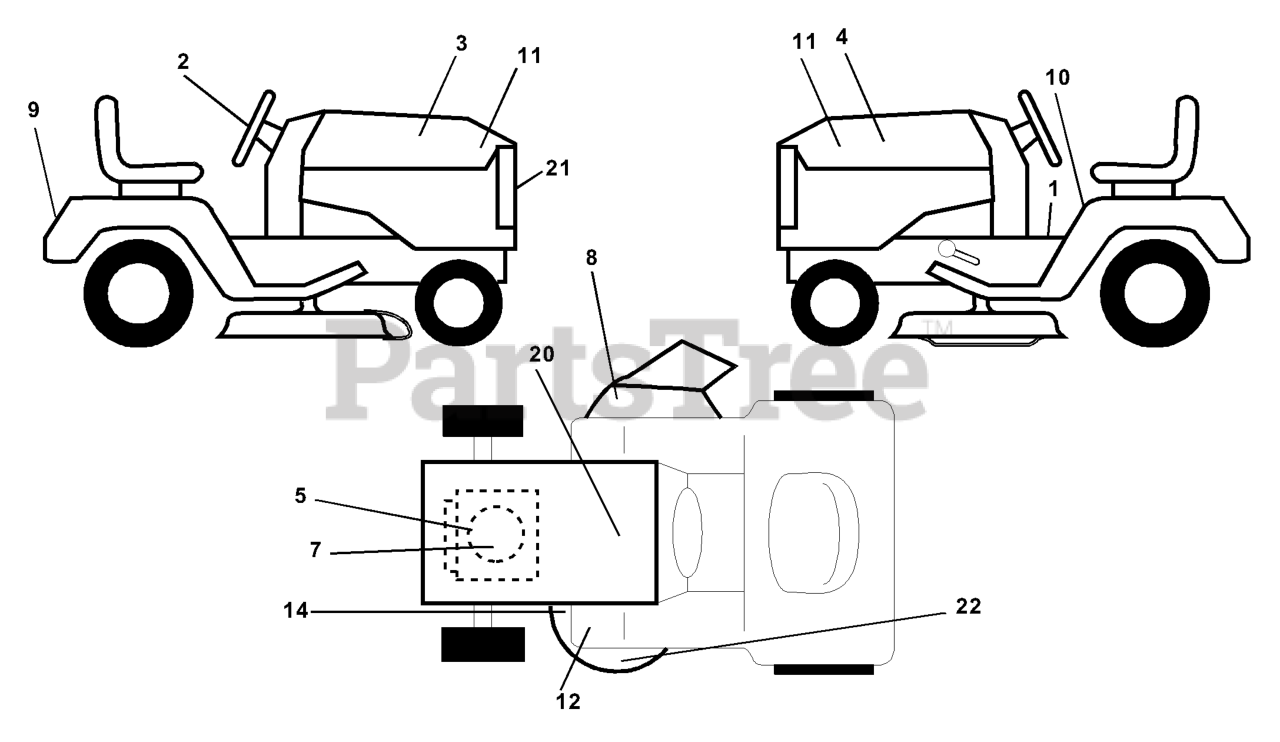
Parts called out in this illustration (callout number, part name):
2	DECAL.WHEEL.STEERING.HUSQ.PERM
3	DECAL HOOD RH
4	DECAL HOOD LH
5	DECAL, ENGINE
7	DECAL, ENGINE LOGO
8	DECAL.WARN.KEEP.HAND.AWAY
9	DECAL, FENDER
10	DECAL FENDER DANGER
11	DECAL, HOOD SIDE
14	DECAL V-BELT SCHEMATIC
20	DECAL BTRY SYMBOLS
21	DECAL.GRILLE.HUSQ
22	DECAL CLUTCH/BRAKE
